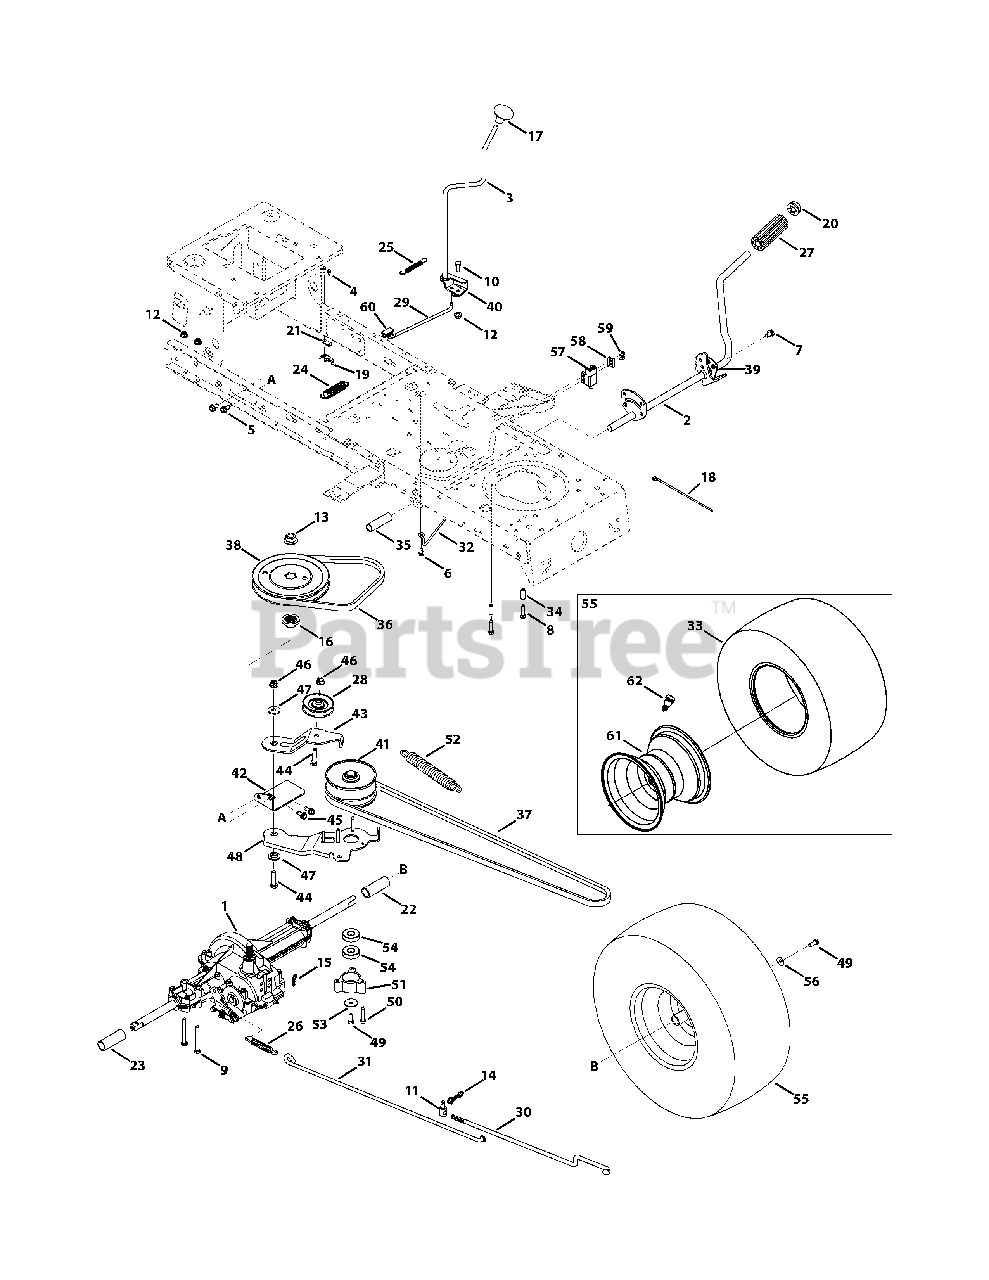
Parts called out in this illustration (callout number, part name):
1	Transmission Drive Assembly
2	Pedal Assembly - Black
2	Pedal Assembly - Red
3	Shaft Lever Assembly
4	Screw, 8-18:0.500
5	Screw, 5/16-18 x .750
6	Screw, 1/4-20 x 0.500
7	Screw, 5/16-18 x 0.625
8	Screw, 1/4-20 x 1.250
9	Hex Screw, 5/16-18 x 2.75
10	Hex Screw, 5/16-18 x .75
11	Ferrule, 3/8-24 X .375 DIA.
12	Flangelock Nut, 5/16-18
13	Flange Nut, 9/16-18
14	Cotter Pin INT- .125 DIA
15	Bow-Tie Cotter Pin, 72
16	Pulley Hub, 5/8 SPLINE
17	Shift Knob
18	Cable Tie
19	Short Springing Switch
20	Push Cap, 5/8
21	Plate Insulator Nut
22	Sleeve, .758 x .821 x 3.3125
23	Sleeve, .758 x .821 x 2.4375
24	Springing Extension, .80 OD x 3.28 LG
25	Springing Extension, .38 OD x 3.25 LG
26	Springing Extension, .59 OD x 4.00 LG
27	Foot Pad, 4.0 LONG
28	Idler Pulley
29	Shift Rod, 38/42"
30	Variable Speed Control Rod
32	Belt Keeper Rod
33	Tire, 20 X 8 X 8 Sq Shoulder
34	Spacer, .260 x .375 x 1.030 LG
35	Spacer, .640 ID x .76 OD x 2.63
36	V Belt, 5L 35.25 POLY
37	V Belt, 5L 70.90 POLY
38	V Pulley 7.25 DIA SPUN
39	Pedal Support Bracket - Black
39	Pedal Support Bracket - Red
40	Shaft Adjust Bracket
41	Variable Speed Pulley Assembly
42	Transmission Bracket Assembly
43	Idler Bracket Assembly
44	Hex Screw, 3/8-16 x 1.75
45	Screw, 5/16-18 x 0.750
46	Flangelock Nut, 3/8-16
47	Shoulder Spacer, .625 ID x .169
48	Bracket Assembly
49	Hex Screw, 5/16-24 x .750
50	Screw, 1/4-20 x 1.500
51	Bearing Cup
52	Extension Springing, .94 OD x 6.75 LG
53	Flat Washer, .330 x 1.25 x .06:HT
54	Ball Bearing, 17 x 40 x 12
55	Wheel, 20 x 8 x 8
56	Bell Washer, .340 x .872 x .060
57	Switch Interlock
58	Plate Switch
59	Shoulder Screw, #10-32 x .500
60	Shift Plate Bearing
61	Rim, 8.0 x 7.0 x .750, 38/42
62	Valve, tubeless Air
